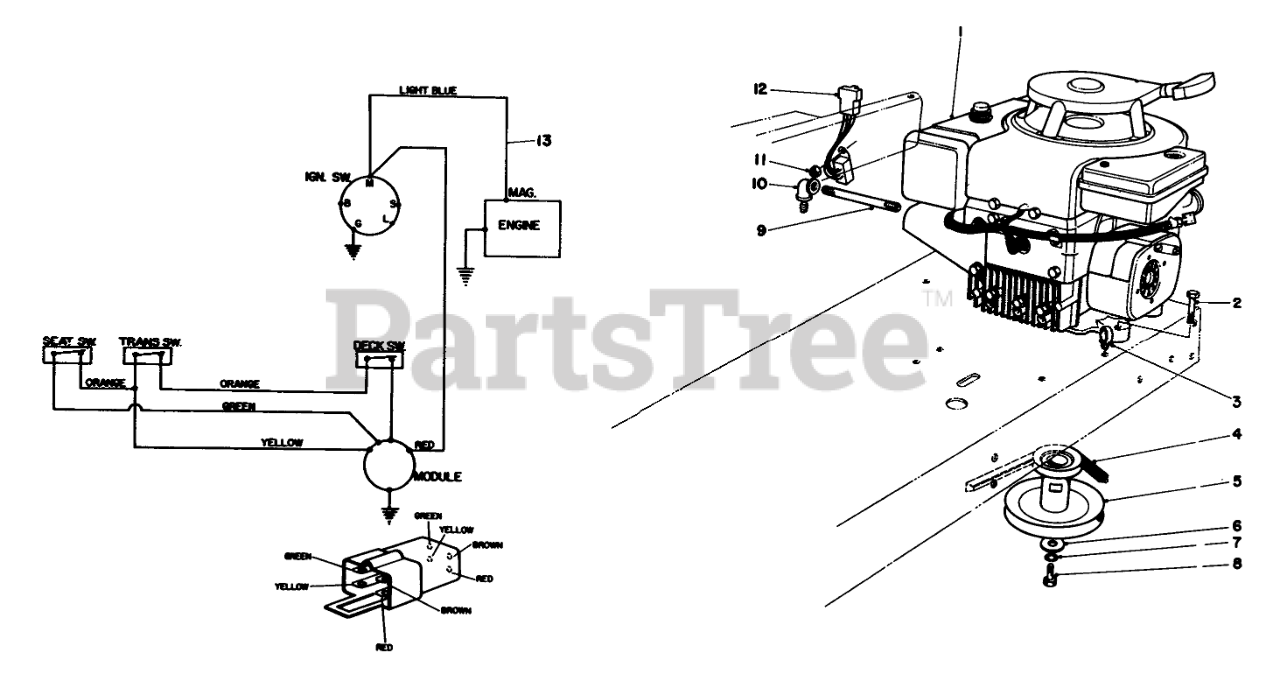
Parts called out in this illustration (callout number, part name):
1	Engine
2	SCREW-HH
3	Clip-Cable
4	V-BELT, TRACTION
5	PULLEY
6	WASHER
7	WASHER-LOCK
8	SCREW-HH
9	NIPPLE
10	ELBOW-90 DEGEE
11	NUT-LOCK, CONE
12	INTERLOCK MODULE
13	Wiring Harness
